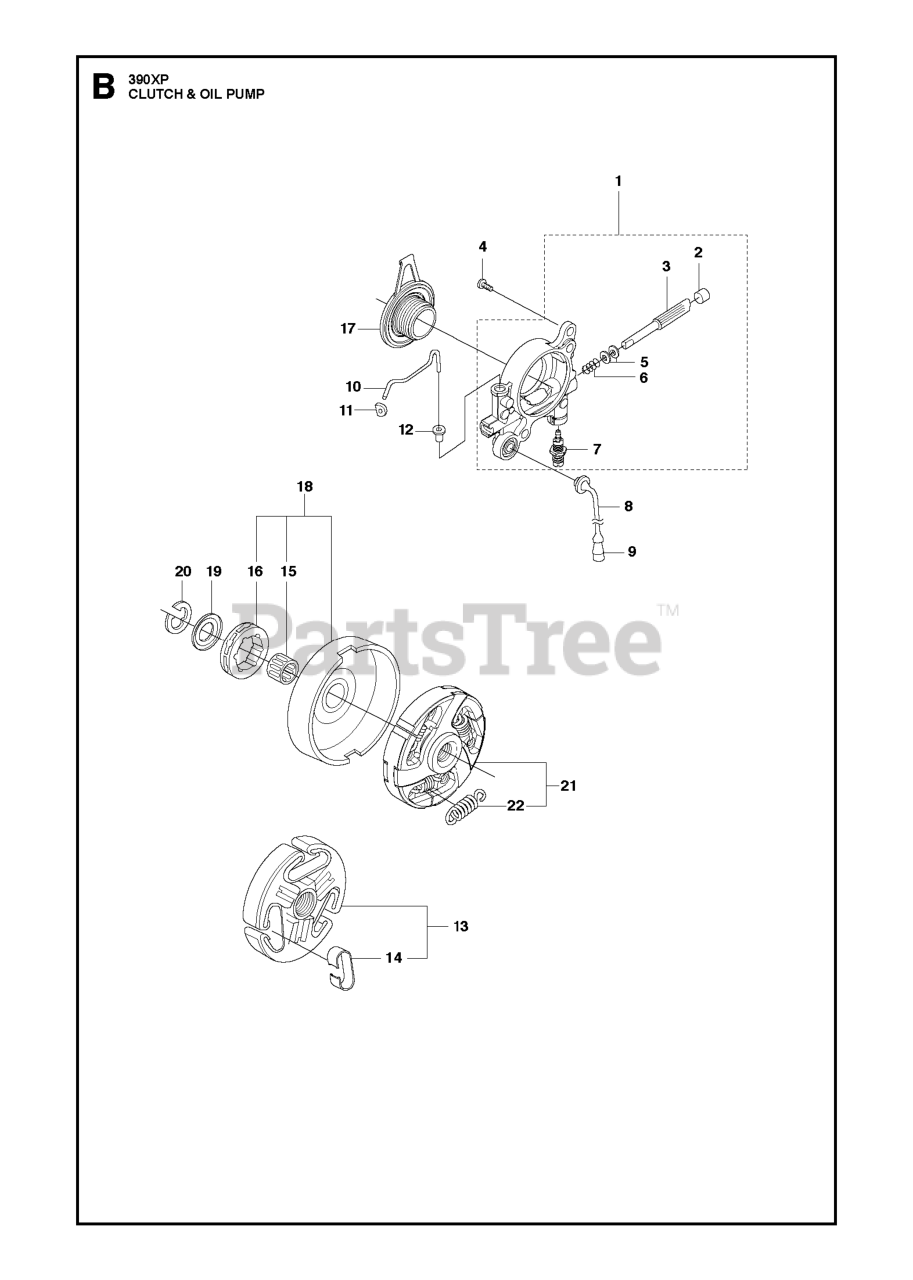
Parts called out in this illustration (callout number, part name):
3	PUMP PISTON
4	SCREW MC6S 5X16
5	WASHER 6.1X9
7	INSERT OIL PUMP
9	OIL SCREEN
13	CLUTCH
14	CLUTCH SPRING
15	CLUTCH DRUM BEARING
16	22273 Sprocket 3/8"x8T
16	22270 RIMSPROCKET
16	68210 RIMSPROCKET
18	CLUTCH DRUM ASSY .404
18	CLUTCH ASSY
20	RETAINING RING
21	CLUTCH ASSEMBLY
22	CLUTCH SPRING
